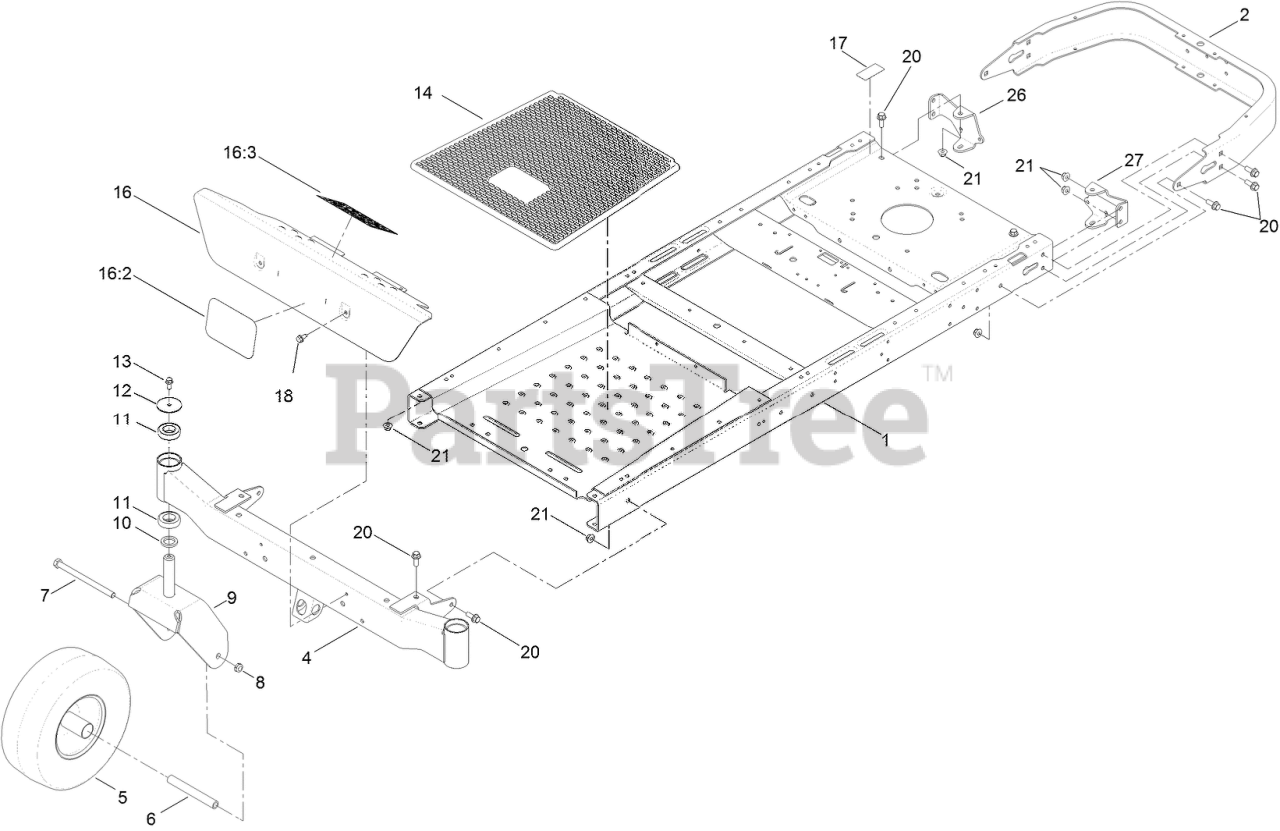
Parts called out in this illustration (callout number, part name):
2	BUMPER-REAR (WIDE)
4	AXLE-FRONT (WIDE)
5	13 INCH WHEEL AND TIRE ASM
6	SPANNER
7	SCREW-HH
8	NUT-LOCK, NI
9	FORK-CASTER
10	WASHER-THRUST
11	BEARING-BALL
12	WASHER
13	SCREW-HHF
14	MAT-FLOOR
16	FOOTREST ASM
16:2	DECAL
16:3	DECAL-DANGER
17	DECAL-BYPASS
18	SCREW-HWHTF
20	SCREW-HHF
21	NUT-HF, NI
26	MOUNT-HYDRO, REAR (RH)
27	MOUNT-HYDRO, REAR (LH)
